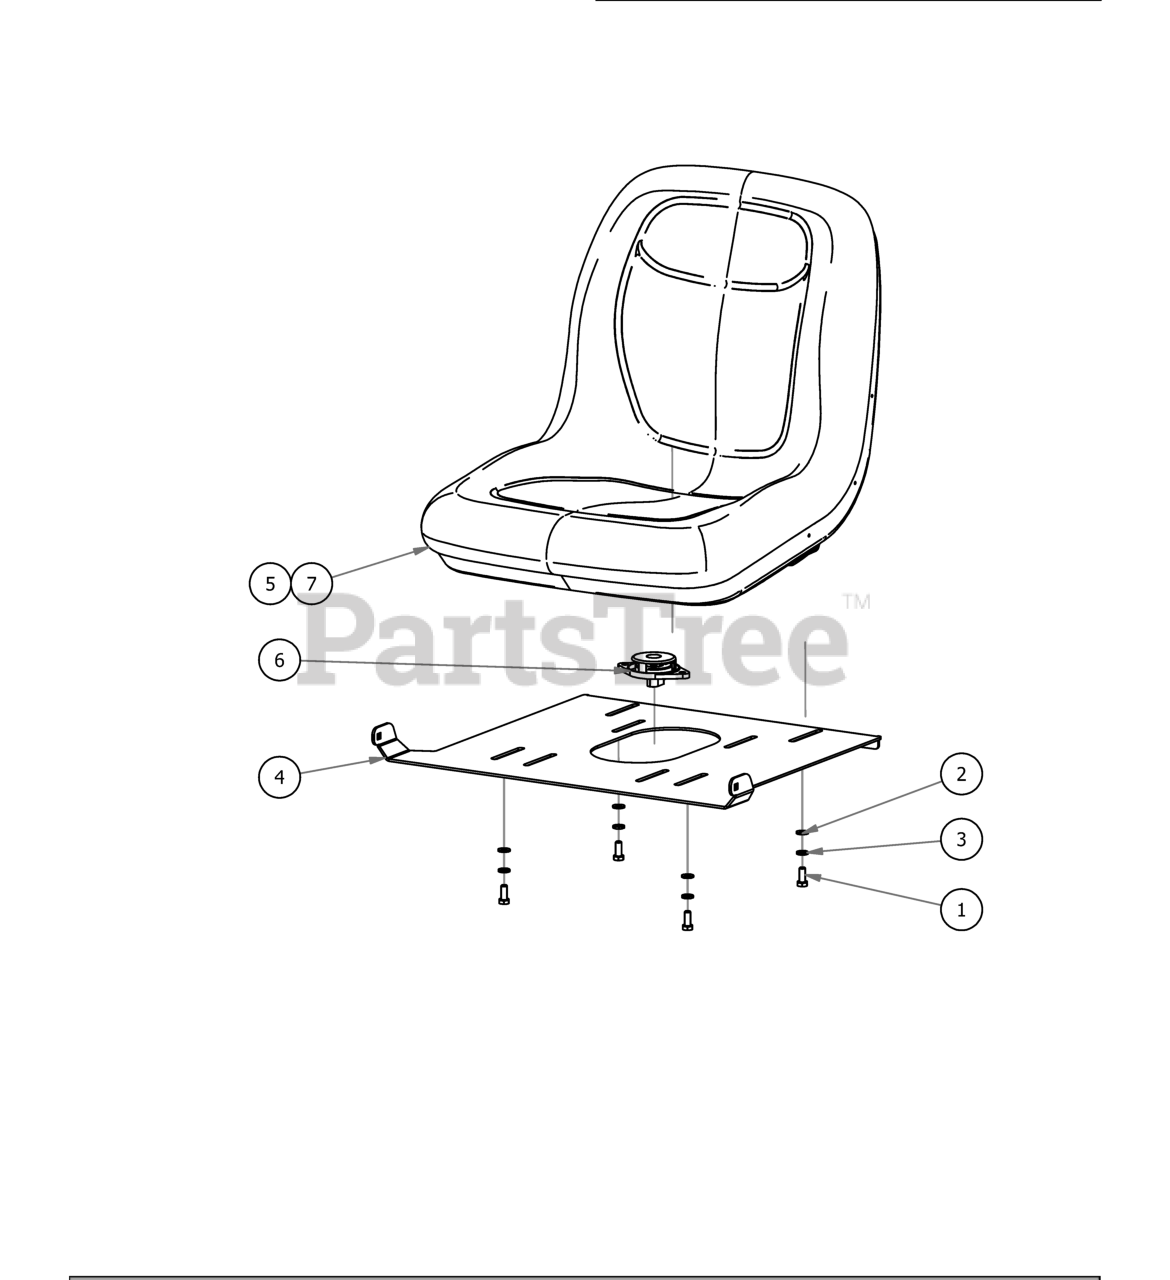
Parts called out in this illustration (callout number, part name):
1	5/16" x 3/4" Hex Bolt
2	1/4" Flat Washer
3	5/16" Lock Washer
4	2017 MZ Seat Plate
5	2019 MZ Magnum Seat
6	SeatSafteySwitch
7	2019 42" MZ Seat
